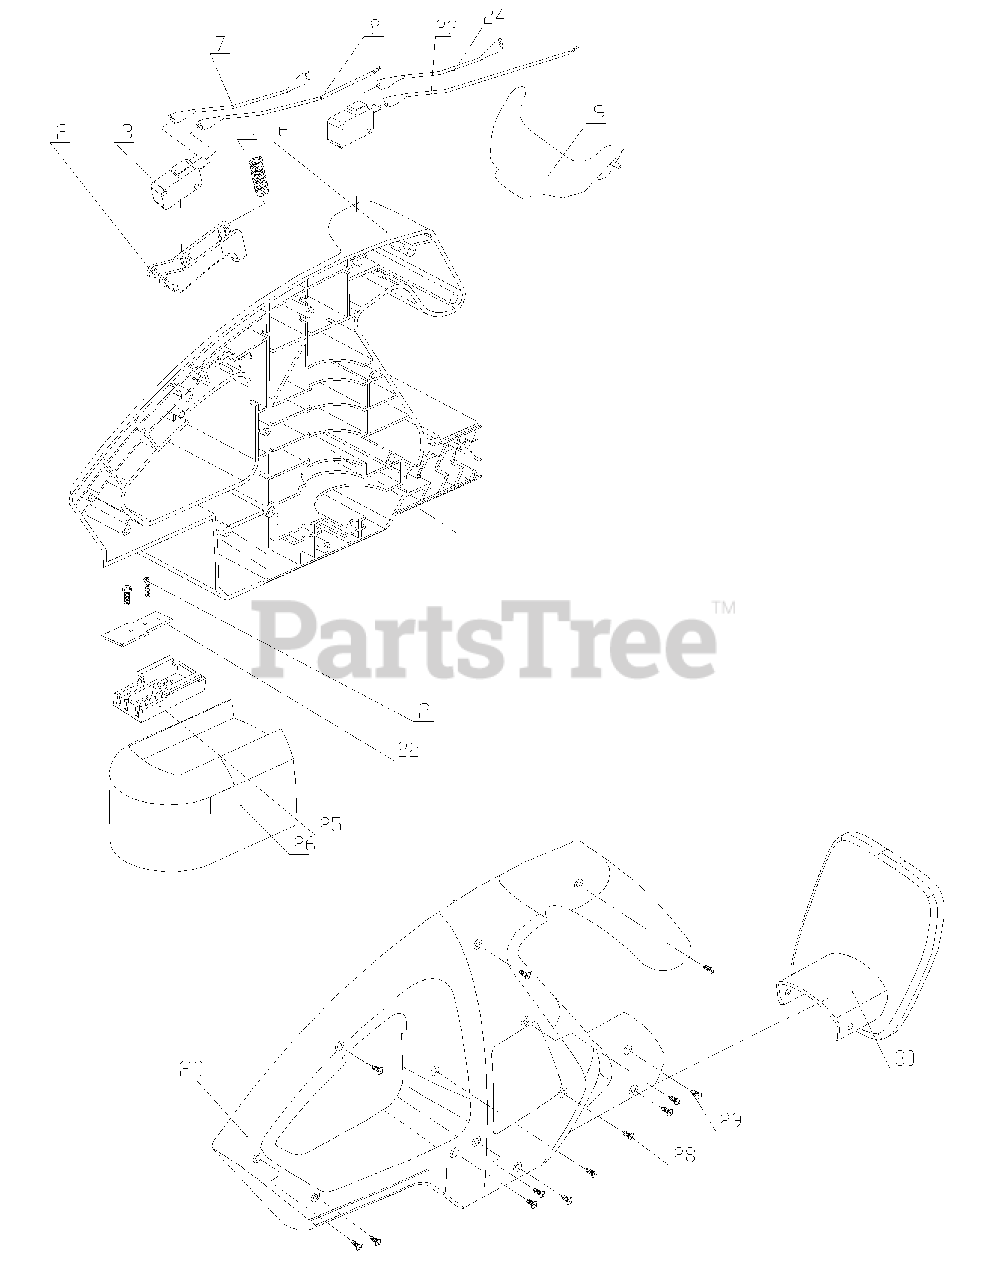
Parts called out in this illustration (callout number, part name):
4	C RING
6	HOUSING (L)
11	MOTOR GEAR
12	LARGE GEAR
15	FIXED BLOCK
19	MIDDLE GEAR
20	HOUSING (R)
25	TERMINAL HOLDER
26	1.9 Ah BYD BATTERY ASS'Y
27	BLADE CONER
